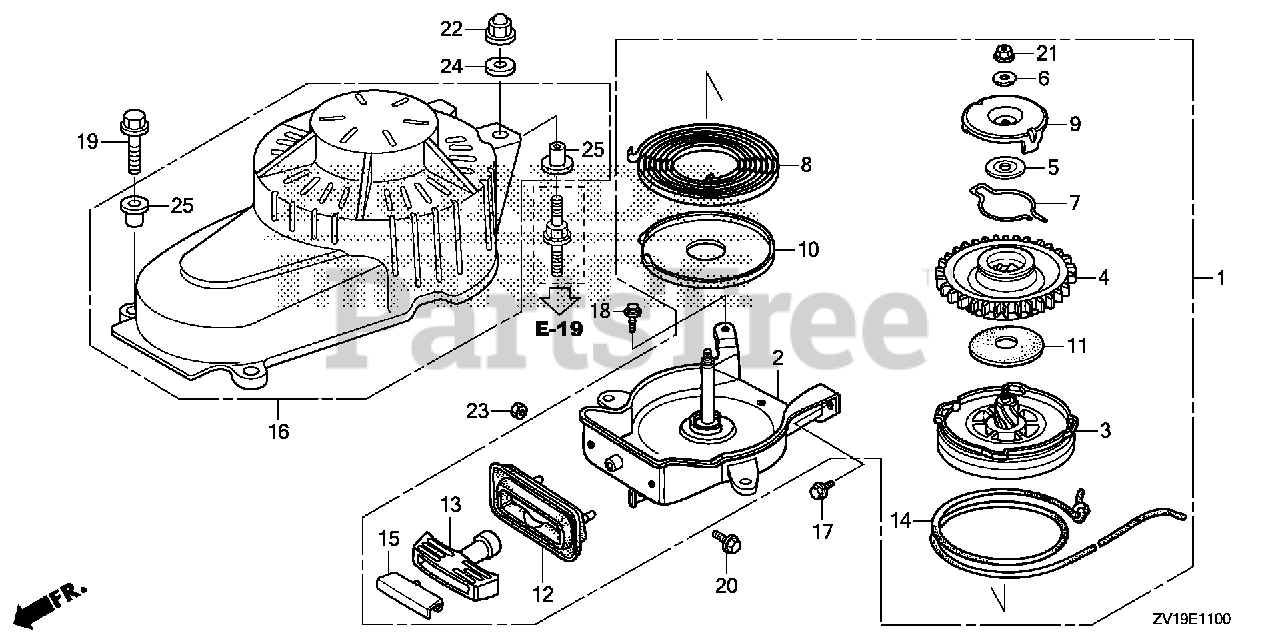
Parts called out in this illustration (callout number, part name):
1	STARTER ASSY., RECOIL *TBLACK* (BLACK)
2	CASE, RECOIL STARTER *TBLACK* (BLACK)
3	PULLEY, RECOIL STARTER
4	GEAR, STARTER
5	WASHER, THRUST
6	WASHER
7	SPRING, FRICTION
8	SPRING, STARTER RETURN
9	RETAINER, SPRING
10	HOLDER, SPRING
11	RUBBER, CUSHION
12	RUBBER, ENGINE COVER SEAL
13	GRIP, STARTER
14	ROPE, RECOIL STARTER (#5.5X79") (N/A: USE P/N 08555-ZG921-11)
16	COVER, FLYWHEEL
17	BOLT, FLANGE (6X12) (CT200)
18	BOLT, FLANGE (6X16)
19	BOLT, FLANGE (6X18)
20	BOLT, FLANGE (6X16)
21	NUT, FLANGE (6MM)
22	NUT, FLANGE CAP (6MM)
23	NUT, HEX. (6MM)
24	WASHER (6.5X18)
25	COLLAR, RECOIL STARTER
